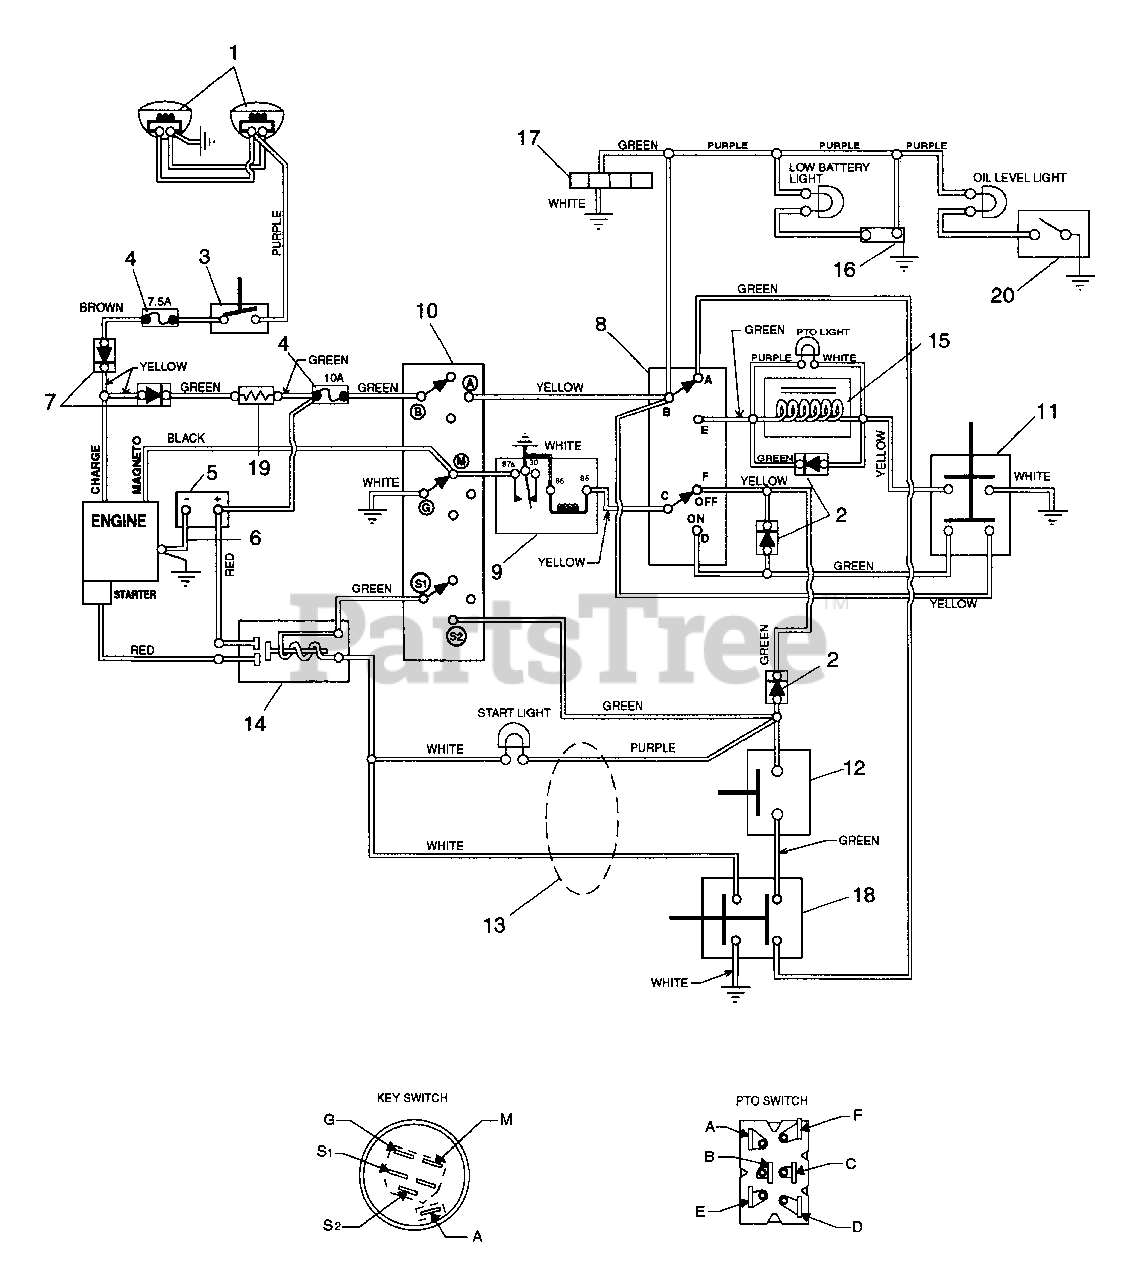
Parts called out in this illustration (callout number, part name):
1	HEADLIGHT- L.H.
1	HEADLIGHT- R.H.
2	MOLDED DIODE PLUG 1 AMP
3	LIGHT SWITCH
4	7.5 AMP FUSE
4	10 AMP FUSE
5	BATTERY
6	GROUND CABLE .31X22.00X.31
7	DIODE & HOUSING
8	SWITCH ASSEMBLY- PTO
9	RELAY
10	KEY SWITCH
11	SWITCH- DOUBLE POLE N.O./N.O.
12	SWITCH-NEUTRAL START N.O.
13	WIRE HARNESS- YT12H
14	SOLENOID
15	ELECTRIC CLUTCH/BRAKE(1.8AMP)
16	VOLTAGE SENSOR
17	HOUR METER W/ LEADS
18	SWITCH- DOUBLE POLE N.C./N.C.
19	RESISTOR- 1 OHM 25 WATT
19	REGULATOR KIT
20	VOLTAGE SENSOR
